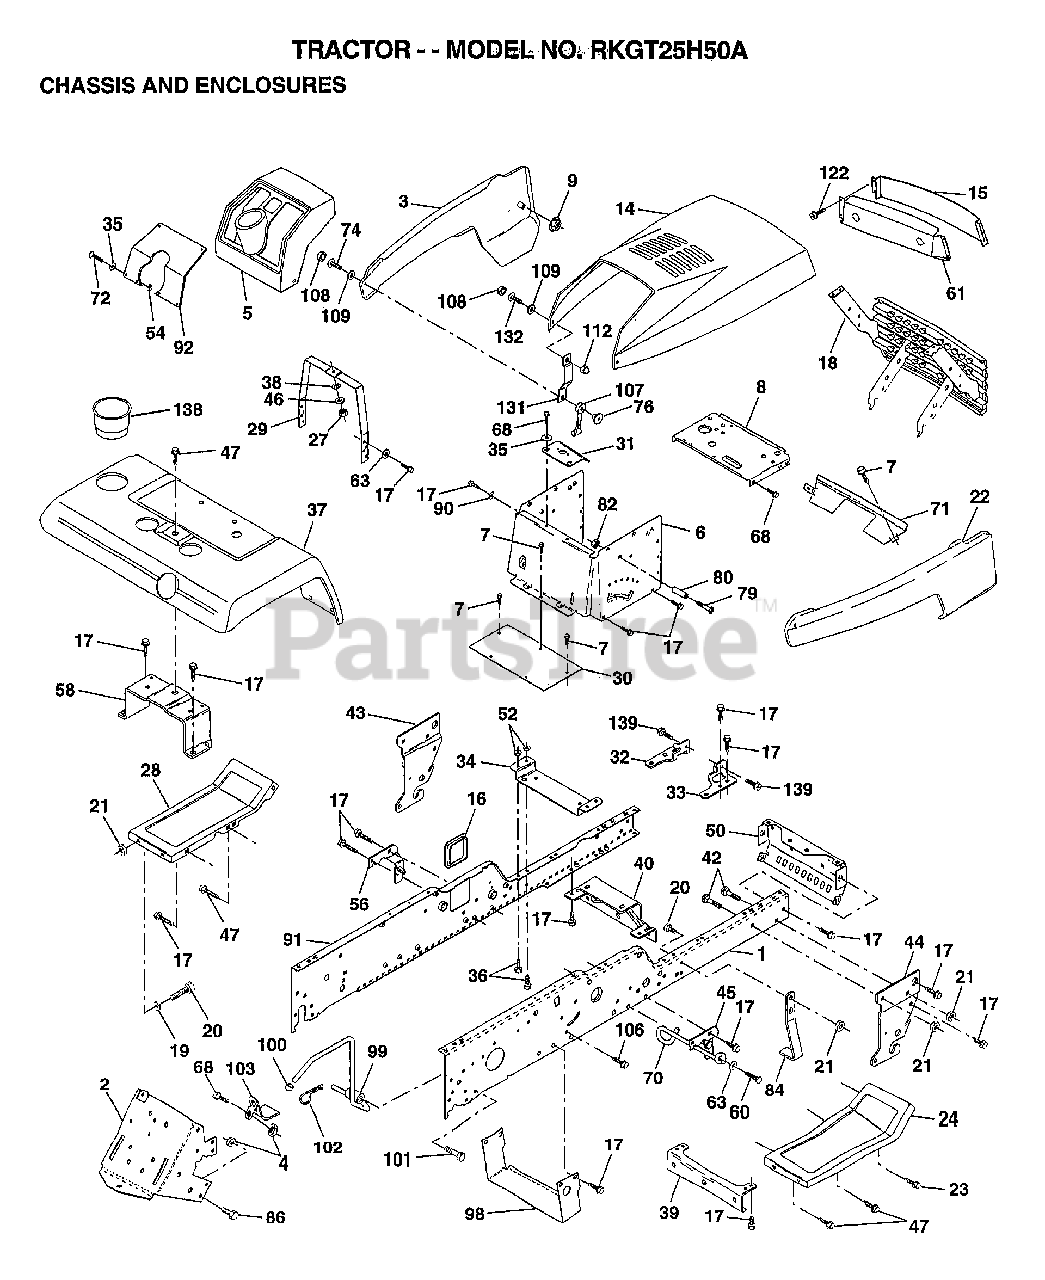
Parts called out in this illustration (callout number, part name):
1	"RAIL,FRAME RH"
2	DRAWBAR GT
3	"PANEL ASM-SIDE,LH"
4	NUT.7/16
5	DASHBOARD BLACK
6	DASH LOWER
7	SCREW
8	SUPPORT.DASH.BTRY
9	PAL NUT LT
14	"HOOD, YARD PRO"
15	LENS.BAR.CLEAR
16	COVER ACCESS
17	SCREW
19	WASHER
20	BOLT
23	SCREW GTV
24	FOOTREST.RH.LT/GT
28	FOOTREST PNT LH
29	DASH.SUPT.YP/HUSQ
30	SADDLE.HYDRO.95
31	BRKT SUPT 1-PC VG
32	BKRT.PIVOT.CHASSIS.LH
33	BKRT.PIVOT.CHASSIS.RH
34	BRACKET.ENG.SUPT.
35	WASHER
36	BOLT
38	LOCKWASHER
39	BRACKET.AXLE.FRT.
40	"BRKT SUPPORT,AXLE"
43	BRACKET.SUS.FT.LH
44	BRACKET.SUS.FT.RH
45	BRACKET.SUSP.RH.
46	WASHER PM
47	SCREW LT
50	"BRKT CHASSIS,FRNT"
56	BRACKET.SUSP.LH.
58	BRKT.ASM.FENDER
60	SCREW
61	BEZEL.1 PC
63	WASHER
68	SCREW LT
70	GUIDE.BELT.MID.SP
72	SCREW
74	SCREW
76	WELDNUT
79	SCREW
80	SPACER LT
84	STOP.OVER.CENTER
86	BOLT
90	LOCKWASHER
91	"RAIL FRAME,LH"
92	PLATE.DASH.SLKS
95	NUT-PUSH YT
98	BRACKET SKID CHAS
99	ROD BYPASS
101	SCREW LT
102	RETAINER M
103	LOCK BYPASS BRKT
107	HOOD LATCH T
108	SNAP CAP LT
109	WASHER LT
112	ACORN NUT RB
120	WASHER HYT
122	SCREW.HEX.WS.HD
131	BKT.SPT.HOOD/PANL
132	SCREW.10-24X3/8.
138	CUPHOLDER.YTGT
139	BOLT.SHOULDER.5/16-18
